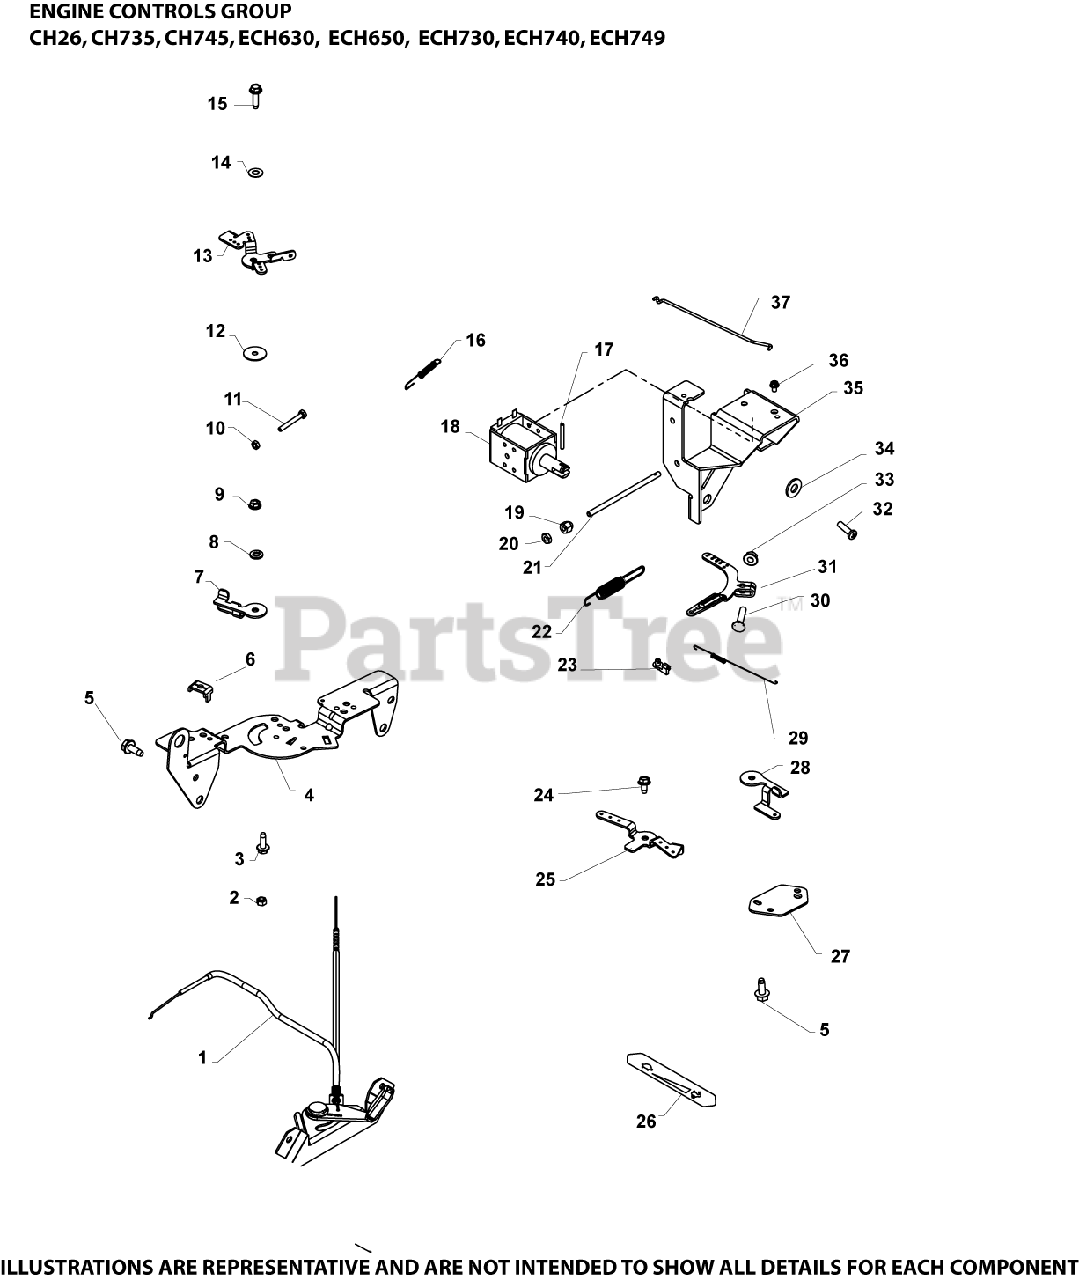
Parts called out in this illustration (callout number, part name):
2	NUT, LOCK M5X.8
3	SCREW, THREAD FORMING
4	BRACKET, CONTROL
5	SCREW, THREAD FORMING
6	CLAMP, CABLE
8	WASHER, SPRING LOCK 1/4"
9	NUT, FLG M5X.8
10	NUT, M4X0.7
11	SCREW, CAP M4X.7X30
12	WASHER, FLAT 5.5 MM
13	LEVER, THROTTLE CONTROL
14	WASHER, SPRING 1/4"
15	SCREW, THREAD FORMING - USE 25 086 473-S
16	SPRING, THROTTLE LIMITER
22	SPRING, GOVERNOR (PURPLE)
23	BUSHING, THROTTLE LINKAGE
28	LEVER, THROTTLE ACTUATOR
29	SPRING, LINKAGE
30	BOLT, RD HD SQ NECK M6X1.0X25
31	LEVER, GOVERNOR ASSEMBLY
33	NUT, FLG M6X1.0
37	LINKAGE, THROTTLE
